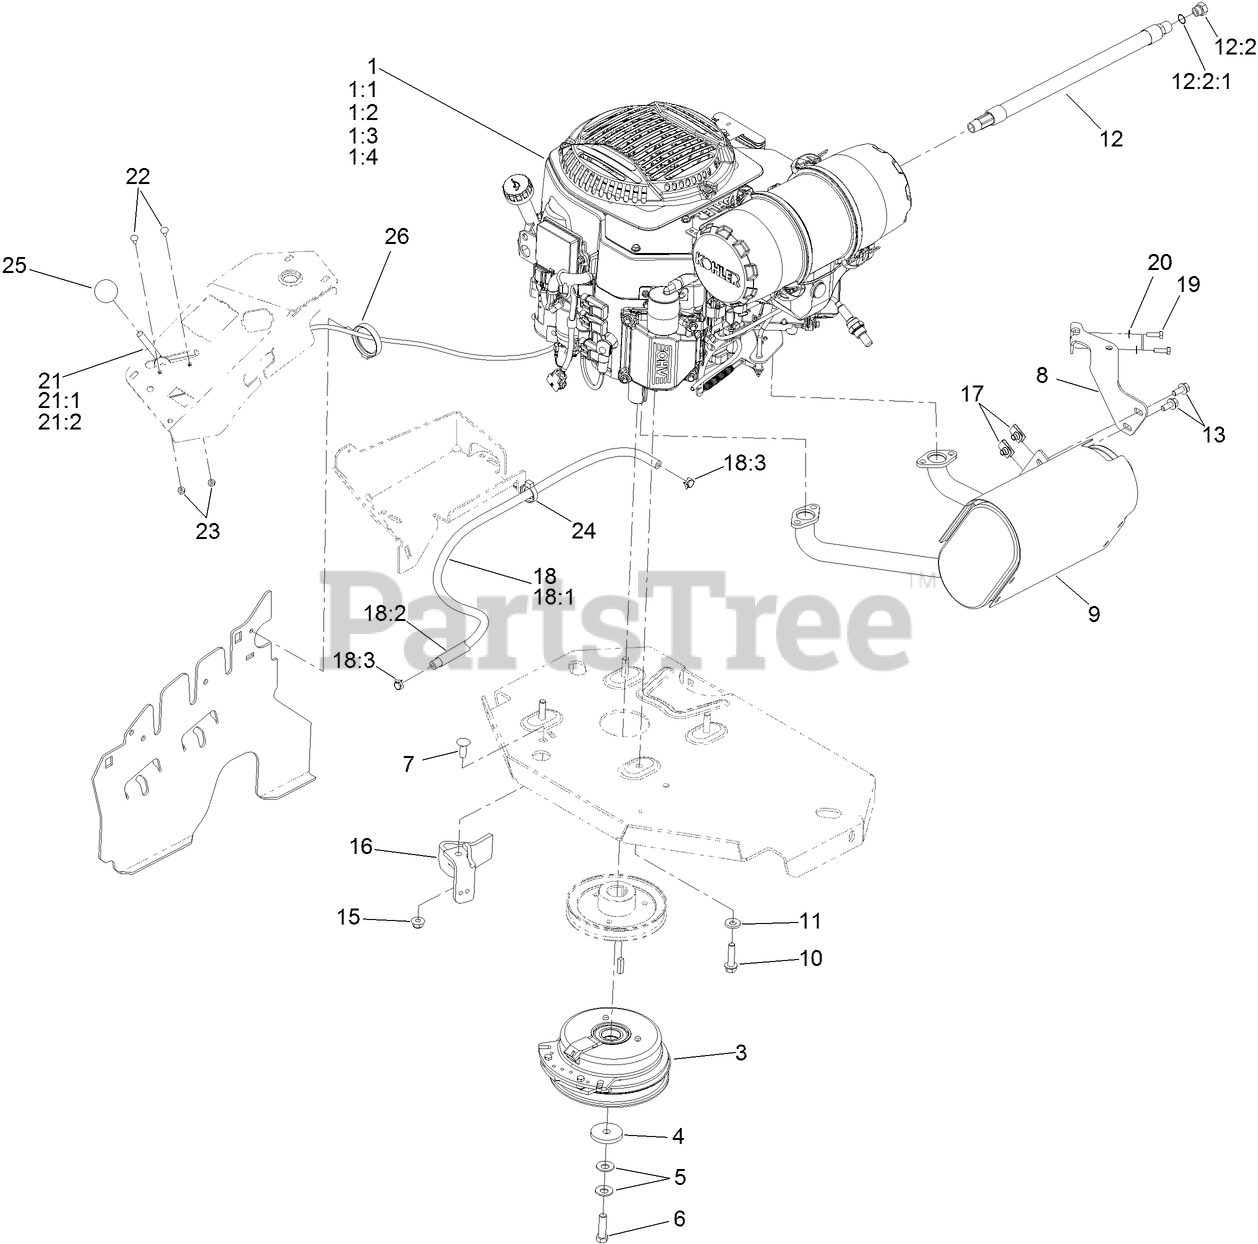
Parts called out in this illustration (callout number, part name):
1:1	KOHLER 52 050 02-S ENGINE OIL FILTER
1:2	KOHLER 25 083 01-S ENGINE AIR FILTER
1:3	KOHLER 25 083 04-S SAFETY FILTER
1:4	KOHLER 25 050 42-S FUEL FILTER
3	CLUTCH KIT
4	WASHER-CLUTCH
5	WASHER-SPRING
6	SCREW-HH, W/LOCTITE
7	SCREW-CARR
8	MUFFLER BRACKET KIT
9	MUFFLER KIT
10	SCREW-HWH
11	WASHER-BELLEVILLE
12	OIL DRAIN HOSE ASM
12:2	PLUG-HH
12:2:1	O-RING
13	SCREW-HH
15	NUT-HF, NI
16	CLUTCH-ANCHOR
17	NUT-U
18	FUEL LINE ASM
18:1	HOSE-FUEL
18:2	SLEEVE-THERMAL
18:3	CLAMP-HOSE
19	SCREW-HH
20	WASHER-SPRING
21	THROTTLE CONTROL ASM
21:1	LEVER-THROTTLE
22	BOLT-CARR
23	NUT-LOCK, NI
24	CLAMP-HOSE
25	KNOB-BALL
26	CLAMP-HARNESS
